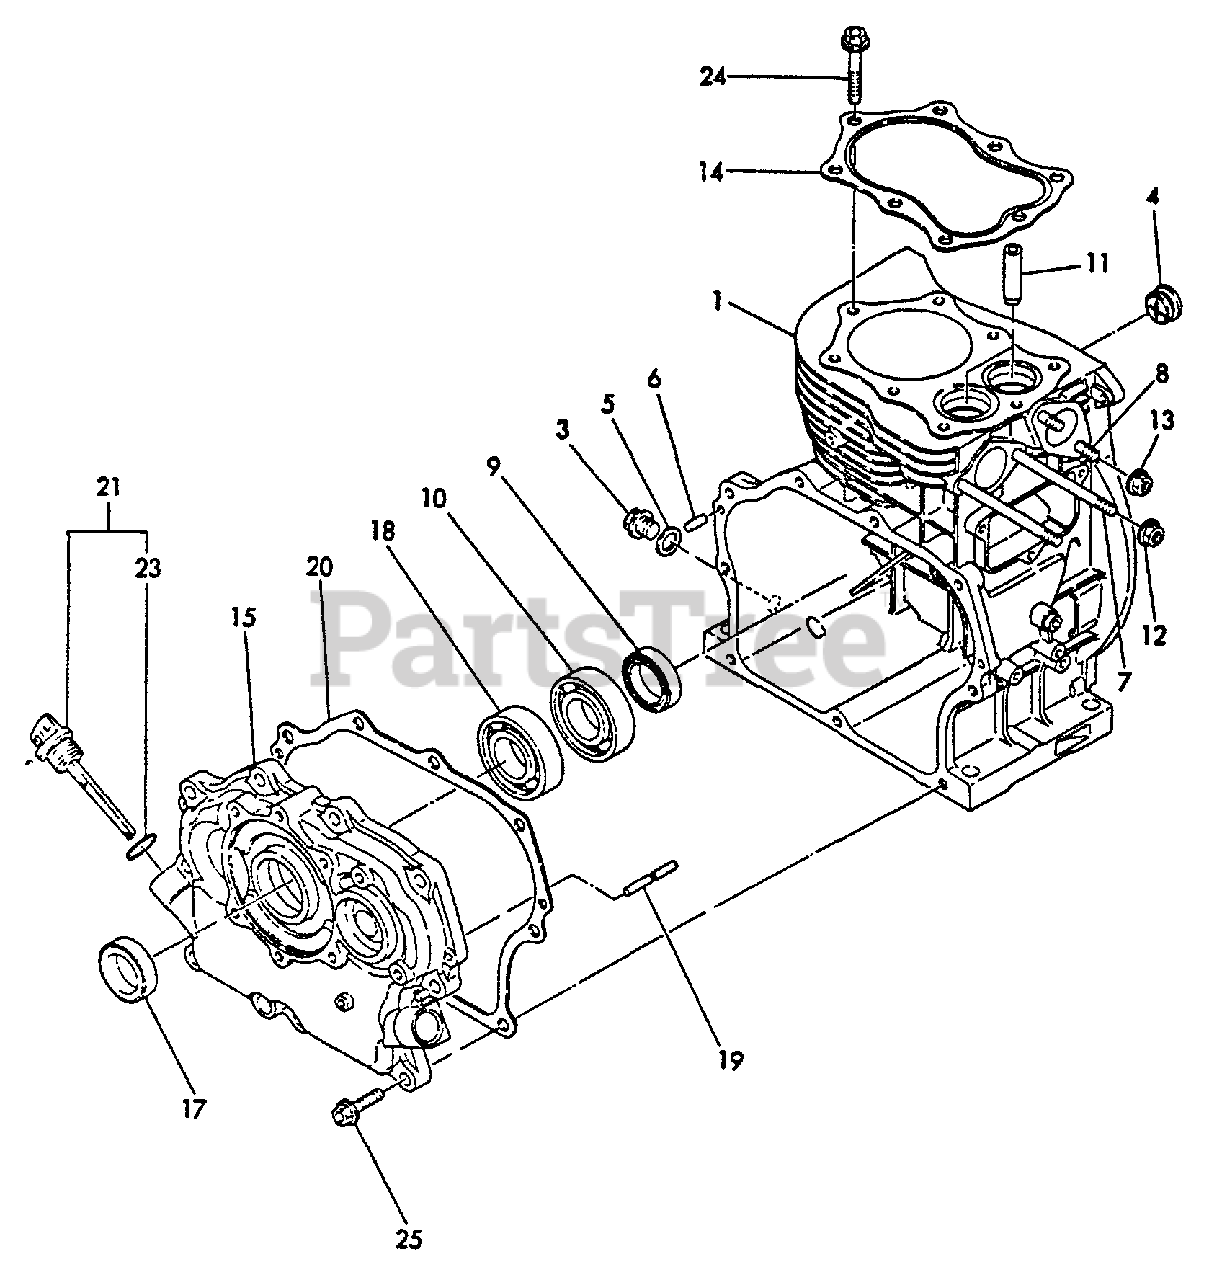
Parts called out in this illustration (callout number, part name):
1	CYLINDER BODY ASSY
3	PLUG, DRAIN
4	PLUG
5	GASKET
6	PIN - 6X16
7	STUD - 8X95 -- PLATED
8	STUD -- PLATED
9	SEAL, OIL
10	BEARING, BALL - 6206C4
11	GUIDE, VALVE
12	NUT - 8
13	NUT - 8
14	GASKET, CYLINDER
15	COVER, CRANKCASE
17	SEAL, OIL
18	BEARING, BALL - 6206C4
19	SHAFT, GOVERNOR
20	GASKET, CRANKCASE
21	CAP ASSY
23	O-RING - 18
24	BOLT - 8X50
25	BOLT - 8X30 -- PLATED
